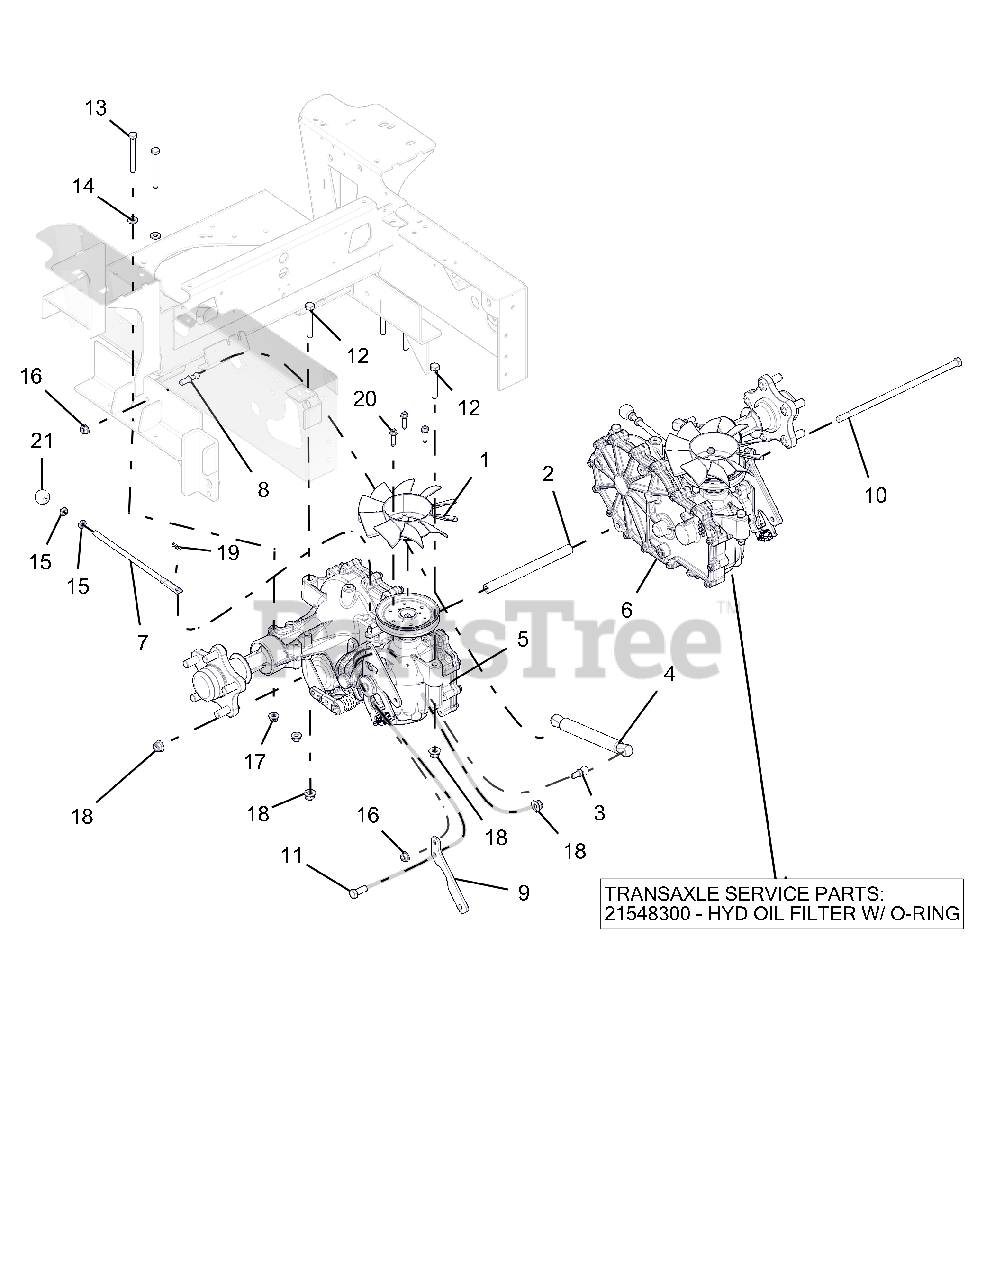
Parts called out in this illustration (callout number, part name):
1	FAN, 2800 SERIES COOLING
2	SPACER, .406 ID X .630 OD X 7.724
3	STUD-BALL
4	DAMPER,
5	TRANSAXLE, ZT3400 - RH
6	TRANSAXLE, ZT3400 - LH
6	HYDRO OIL FILTER W/ O-RING
7	LEVER, PT100 DUMP VALVE
8	STUD, BALL THREADED
9	TRANSMISSION DAMPER MTG PLATE - BLK
10	BLT, HEX .38-16X11.00 GR5 YWZC
11	BLT-HEX .38-16X1.00 GR5 YWZC
12	BLT-HEX .38-16X2.50 GR5 YWZC
13	BLT-HEX .31-18X3.00 GR5 YWZC
14	WSHR-FL-STL.344X.688X.065YWZC
15	NUT, JAM .312-18 YWZC
16	NUT, LK-TOP-FLG .312-18 YWZC
17	NUT-LK-NYL-FLG .31-18 YWZC
18	NUT-LK-NYL-FLG .38-16 YWZC
19	PIN-HAIR INT .06X.18X.77
20	SCR-TAP .25-20X1.00 HWH TR YZ
21	KNOB, BALL -BLACK .312-18
